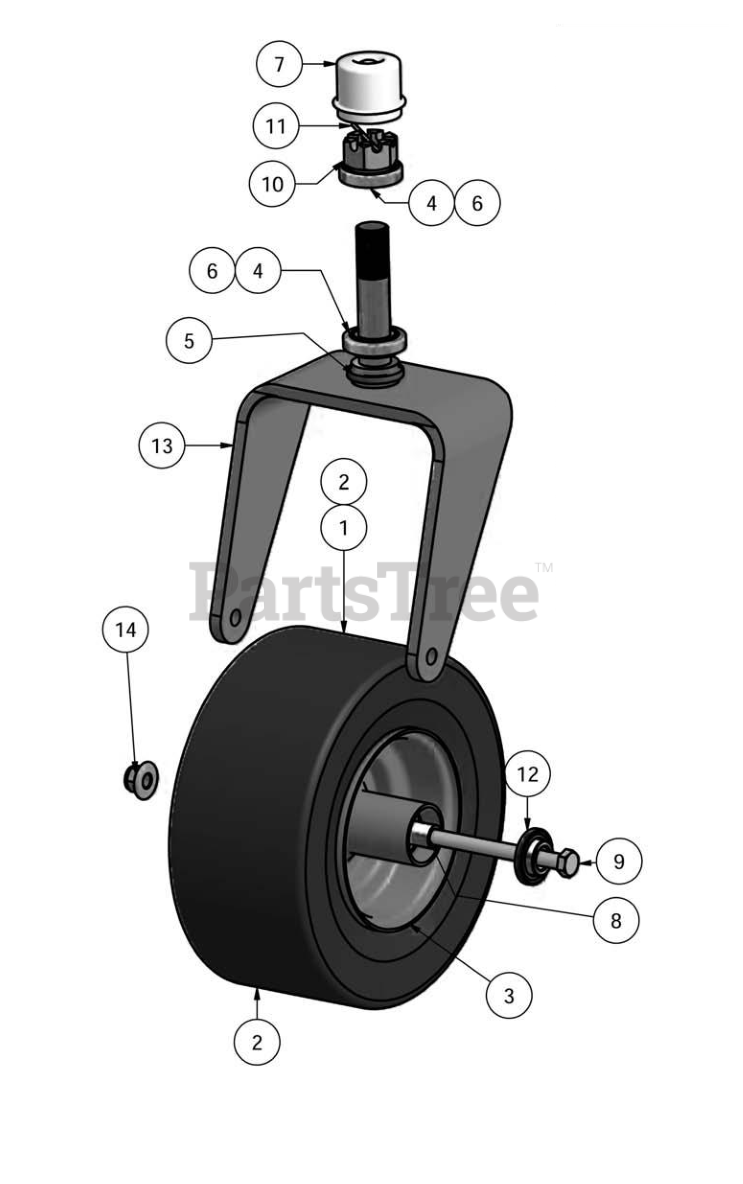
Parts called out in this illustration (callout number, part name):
1	13 x 6.5-6" Tire and Wheel Assembly
2	13 x 6.5-6" Tire ONLY
3	6" Wheel ONLY
7	Dust Cover
8	Wheel Spacer
9	1/2" x 9" Bolt
10	1" Fine Threaded
11	Cotter Pin
12	Wheel Bearing
13	Front Fork with Spindle
14	1/2-13 Nylon Flange Nut
